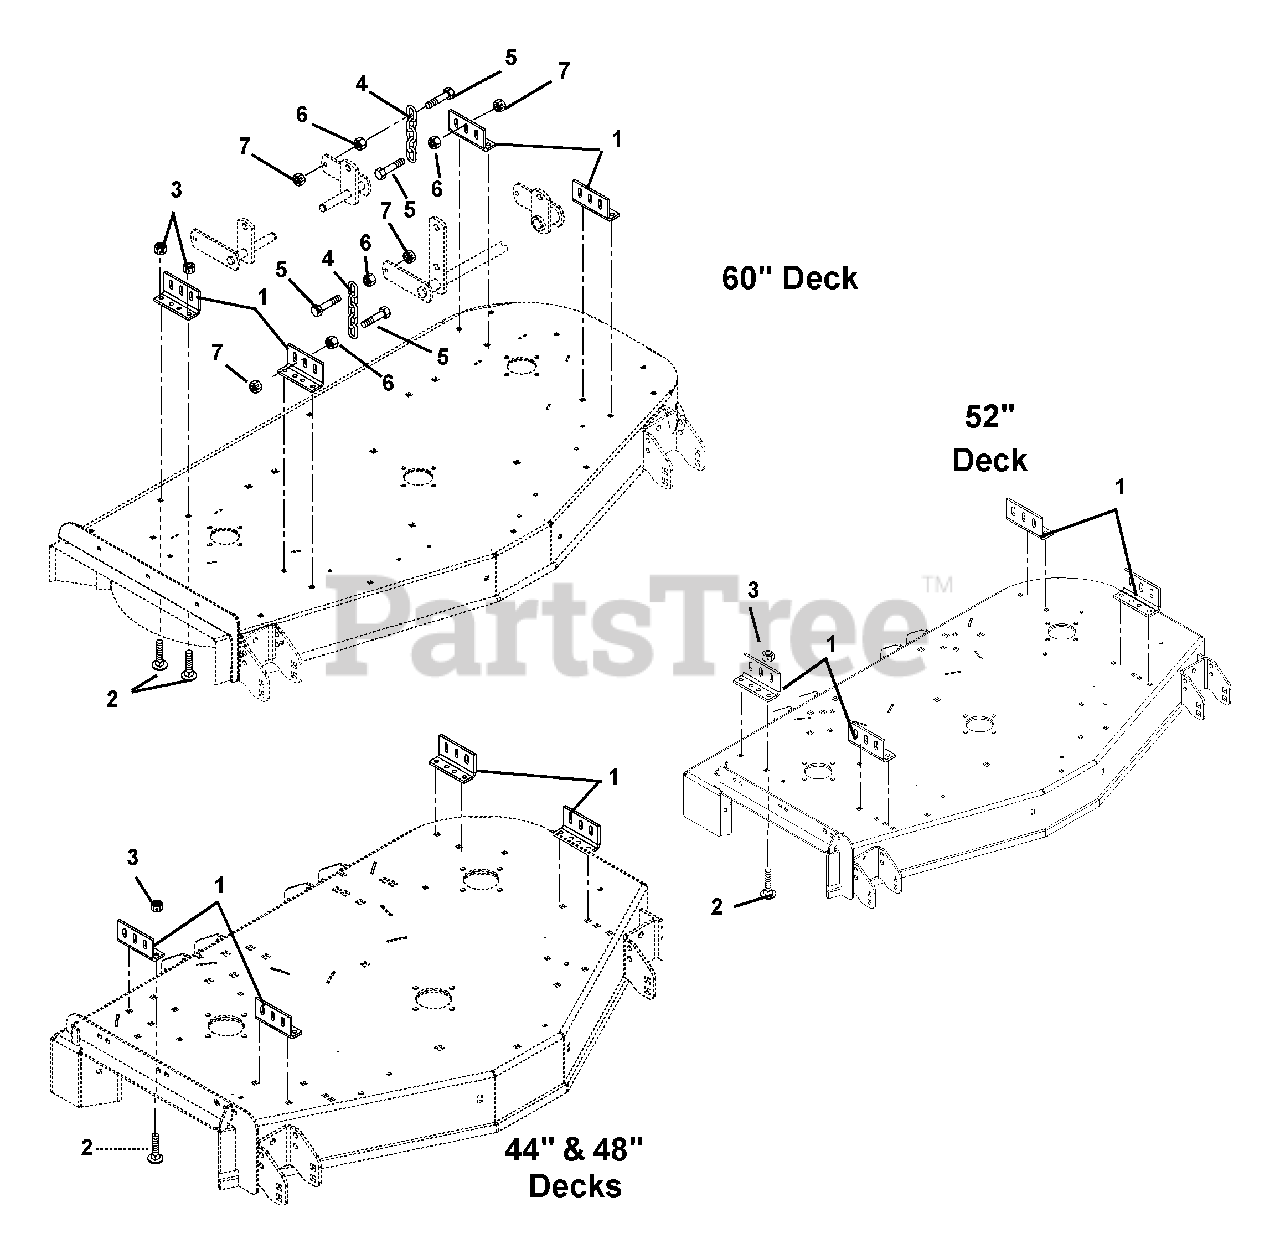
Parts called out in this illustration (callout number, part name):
1	Bracket, Mower Mounting
2	Bolt, Round Head Square Neck .38-16 x 1.00 Grade 2
3	Nut, Locking Top Flange .38-16
4	Chain, Link
5	Bolt, Hex M12-1.75 x 55 Grade 5
6	Nut, Spin Lock Flange M12-1.75
7	Nut, Locking Top Flange M12-1.75
